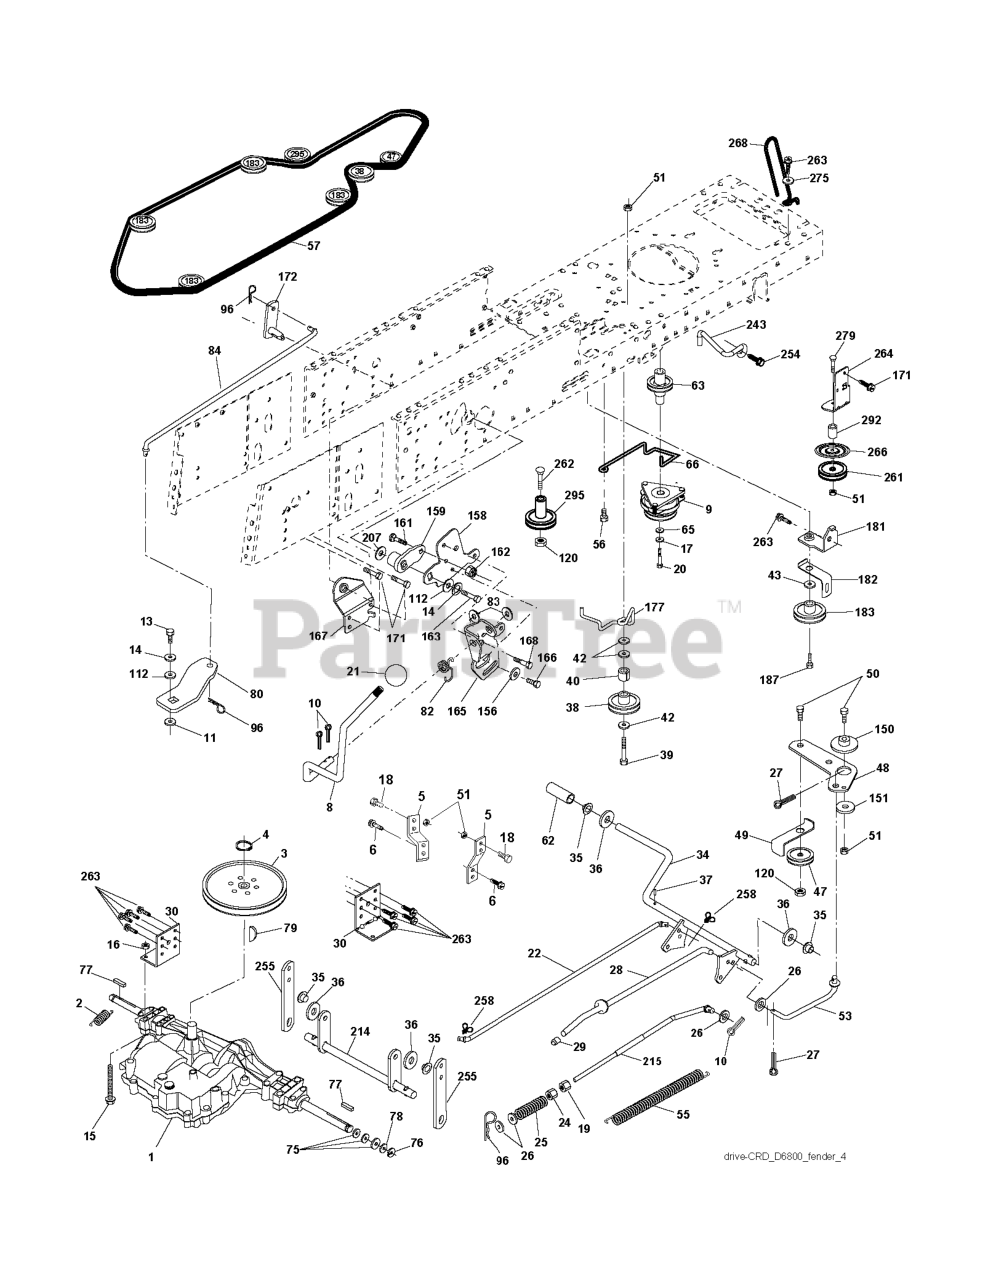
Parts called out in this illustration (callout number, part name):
2	SPRING,BRAKE RETURN
3	PULLEY
4	RETAINING RING LT
5	STRAP TORQUE
6	SCREW 5/16"
8	ROD SHIFT FENDER ADJUST LT
9	CLUTCH.ELECTRIC.OGURA.EURO.
10	PIN COTTER
11	WASH-SHFT PLT LT
13	BOLT 1/4-28X3/4
14	LOCKWASHER
15	BOLT HEX 5/16-18 GR 5
16	NUT.71038.31-18.HEX.NYLOCK
17	LOCKWASHER
19	NUT
20	BOLT HEX 7/16-20X4-1/4"
21	KNOB.DUCKHEAD.1/2
22	ROD
24	NUT
25	SPRING ROD LT
26	WASHER
27	COTTER PIN
28	ROD, PARKING BRAKE
29	CAP
30	BRKT, MOUNT TRNSAXLE
34	SHAFT, FOOT PEDAL
35	BEARING.NYLON
37	DRIVE PIN
38	PULLEY.FLAT
42	WASHER
47	IDLER PULLEY
48	BELLCRANK, CLUTCH
49	RETAIN BELT
50	BOLT.3/8-16X1.50
53	LINK.CLUTCH.7.66.2005
55	SPRING, RETURN LT
56	SCREW.3/8-16
62	PEDAL COVER T
63	PULLEY.ENGINE.CVX.LT
66	KEEPER BELT ENGINE
77	SQUARE KEY
79	KEY STD (1373) DANA
82	SHIFT SPRING
83	WASHER
84	LINK.T/A.CRD.D6800.18"CLR
96	RETAINER M
120	NUT LOCK FLG 3/8-16 UNC
150	BUSHING.BELLCRANK.GRD.DR
151	WASHER 12/32X2X10GA
156	WASHER.SRRTD.5/16
158	BRACKET
159	RB HUB.SHIFT
161	BOLT
162	NUT.CROWNLOCK.1/4
165	RP BRACKET
166	CAPSCREW.HXHD.FLG.5/16-18X.625
167	BRACKET.SUPT.SHIFT.CRD
168	BOLT.SHOULDER.5/16-18X
181	BRACKET
182	BELT GUIDE
183	PULLEY.V-IDLER.GRND.DR
187	BOLT.5/16-18X1.25
207	WASHER NYL
214	LEVER
243	BRACKET, ANTI-ROTATION
254	SCREW 3/8-16X1
255	SHAFT
258	CLIP RETAINER
261	FLAT IDLER PULLEY
263	SCREW, 3/8-16X3/4
266	PROTECTOR
268	GUARD MUFFLER
275	WASHER
292	SPACER
295	PULLEY IDLER COMPOSITE
